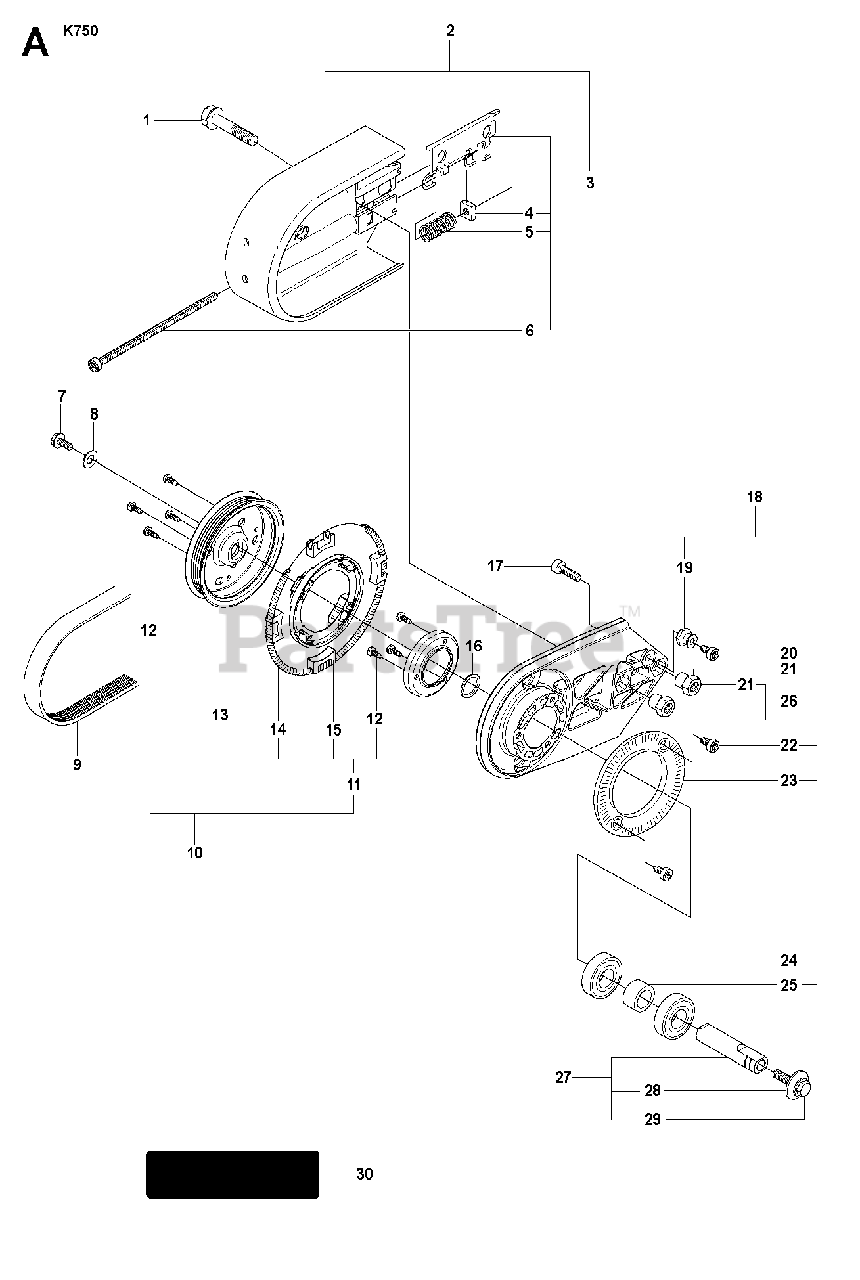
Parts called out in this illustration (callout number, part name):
1	SCREW EHHFM
2	BELT GUARDIncl. 3
3	BELT TENSIONER ASSYIncl. 4 - 6
5	COMPRESSION SPRING
6	SCREW CITXSCM
10	PULLEYIncl. 11 - 13
11	CASSETTEIncl. 12, 14 - 15
12	SCREW CCRPANT
18	BEARING HOUSINGIncl. 19 - 25, 27
19	TORSION STOP
20	SCREW ITXSCM
22	SCREW ITXSCM
24	BALL BEARING
26	BEARING HOUSINGIncl. 21
27	SHAFTIncl. 28, 29
30	LABELJapan only
